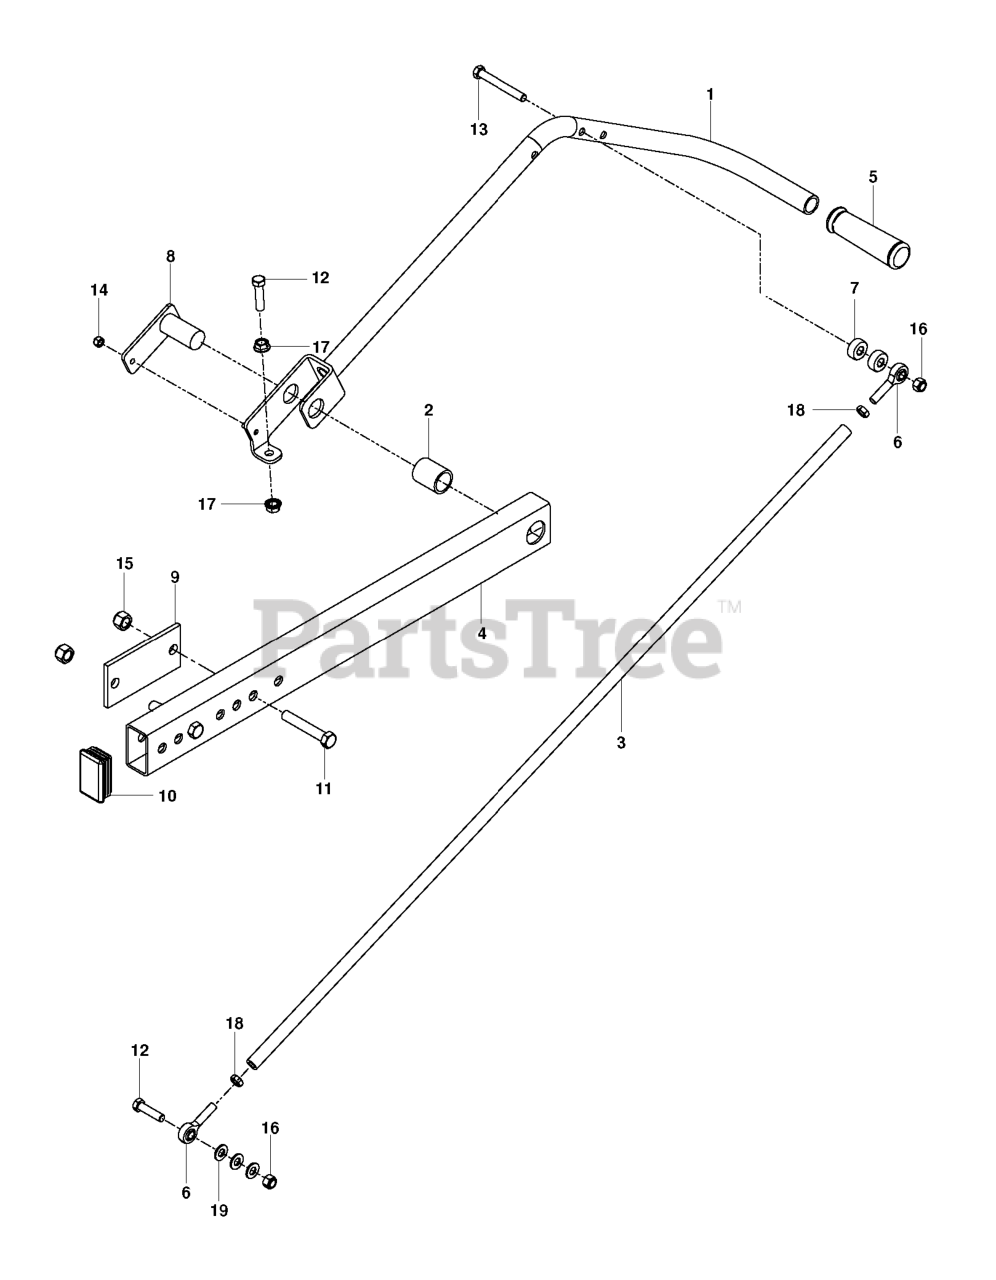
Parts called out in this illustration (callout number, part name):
1	HANDLE BLK
2	BUSHING - BRONZE, 1.0"
3	TUBE - THREADED
4	TUBE.SUPT.HANDLE
5	GRIP.HANDLE.1"ID.BLK
6	ROD END - 3/8-24 RH
8	WELDMENT - PIN, PIVOT
9	PLATE - BACKING
10	PLUG - RETANGULAR TUBING
11	SCREW, 1/2C X 3 HEX CAP
12	HCS 3/8C X 1 1/2
13	HCS 3/8C X 3
14	NUT.1/4-20.HEX.NYLOC.ZD
15	NUT 1/2-13 HEX NYLOC ZD
16	NUT 3/8-16 NYLOC
17	NUT 3/8C WHIZ
18	NUT 3/8-24 JAM
19	WASHER 3/8 SAE FLAT
